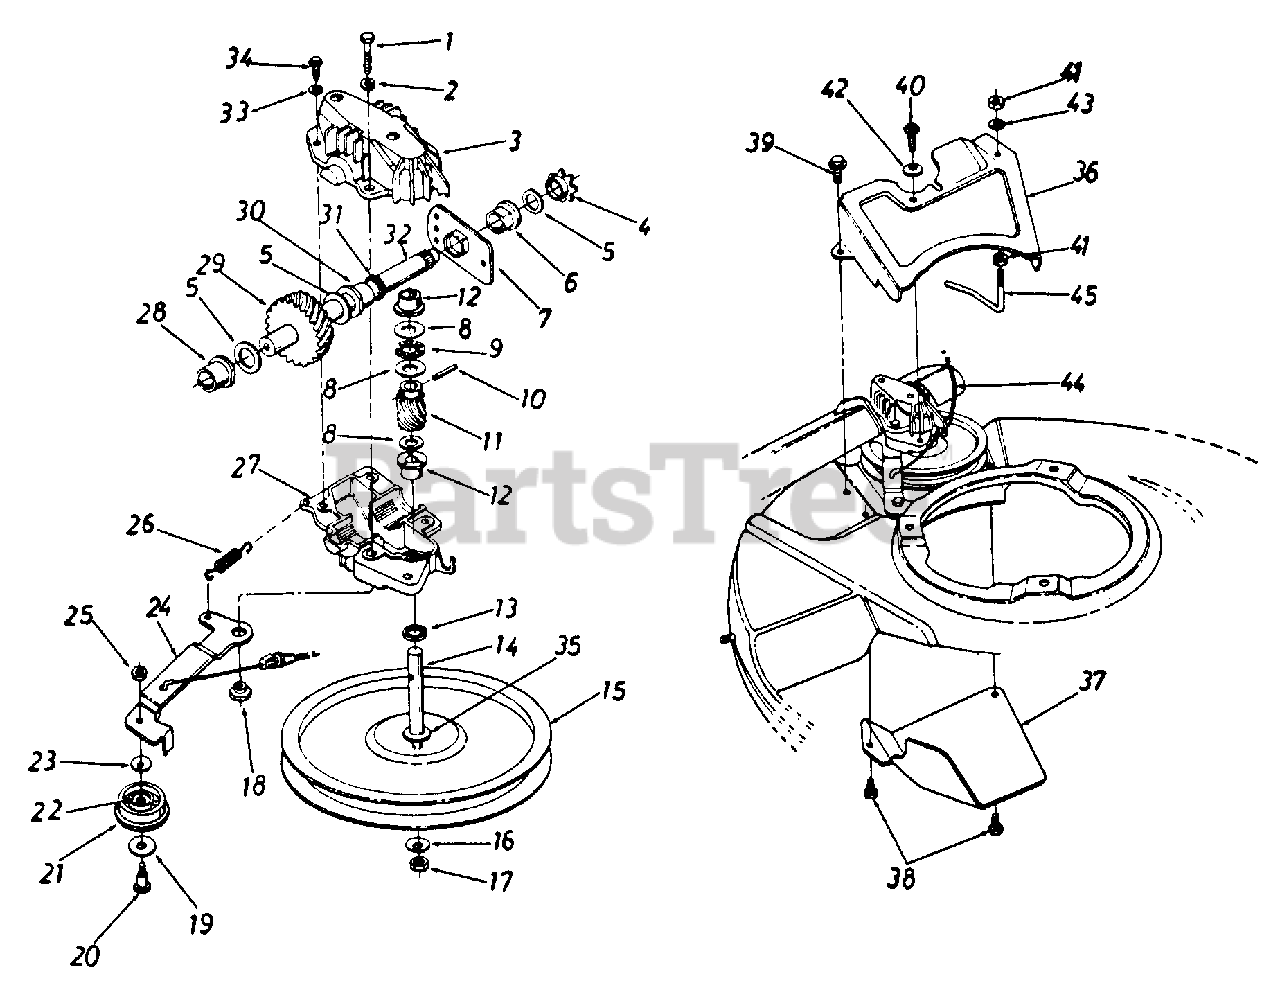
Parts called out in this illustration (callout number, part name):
1	SCREW-HEX 1/4-20 x 1.25
2	LOCK WASHER 1/4 DIA
3	HOUSING HALF-UPPER
4	SPROCKET-7T
5	WASHER-FL
6	BEARING-HEX FLANGE
7	BEARING-CUP HEX
8	WASHER-THRUST.382 x .684
9	BEARING-THRUST
10	PIN-SPRING-SPIR 1/8 x .625
11	GEAR-WORM
12	BEARING-FLANGE
13	SEAL-OIL-.375 ID
14	SHAFT-TRANS
16	WASHER-SPRING BELL
17	NUT-LH THD-1/4 x 28
18	SPACER-SHLD
19	WASHER-FL .995 x .032
20	SCREW-SHLD
21	KIT-PULLEY
22	BEARING-NEEDLE
23	WASHER-SPRING BELL
24	BRACKET ASSY-IDLER
25	NUT-HEX 1/4-28
26	SPRING-EXTENSION
27	HOUSING HALF-LOWER
28	BEARING-FLANGE
29	SHAFT-ASSY W/GEAR
30	BEARING-FLANGE
32	SHAFT-ASSY W/GEAR
33	WASHER-LOCK-#10
34	SCREW-HEX WASH HD TAP
35	WASHER-HEX
36	GUARD-BELT
39	SCREW-HEX WASH SF TAPP
40	SCREW-HEX B-TAP 1/4-.62
41	NUT-HEX 1/4-20
42	WASHER-SPRING BELL
43	LOCK WASHER 1/4 DIA
44	CABLE-CLUTCH x 50.0
45	GUARD-BELT
